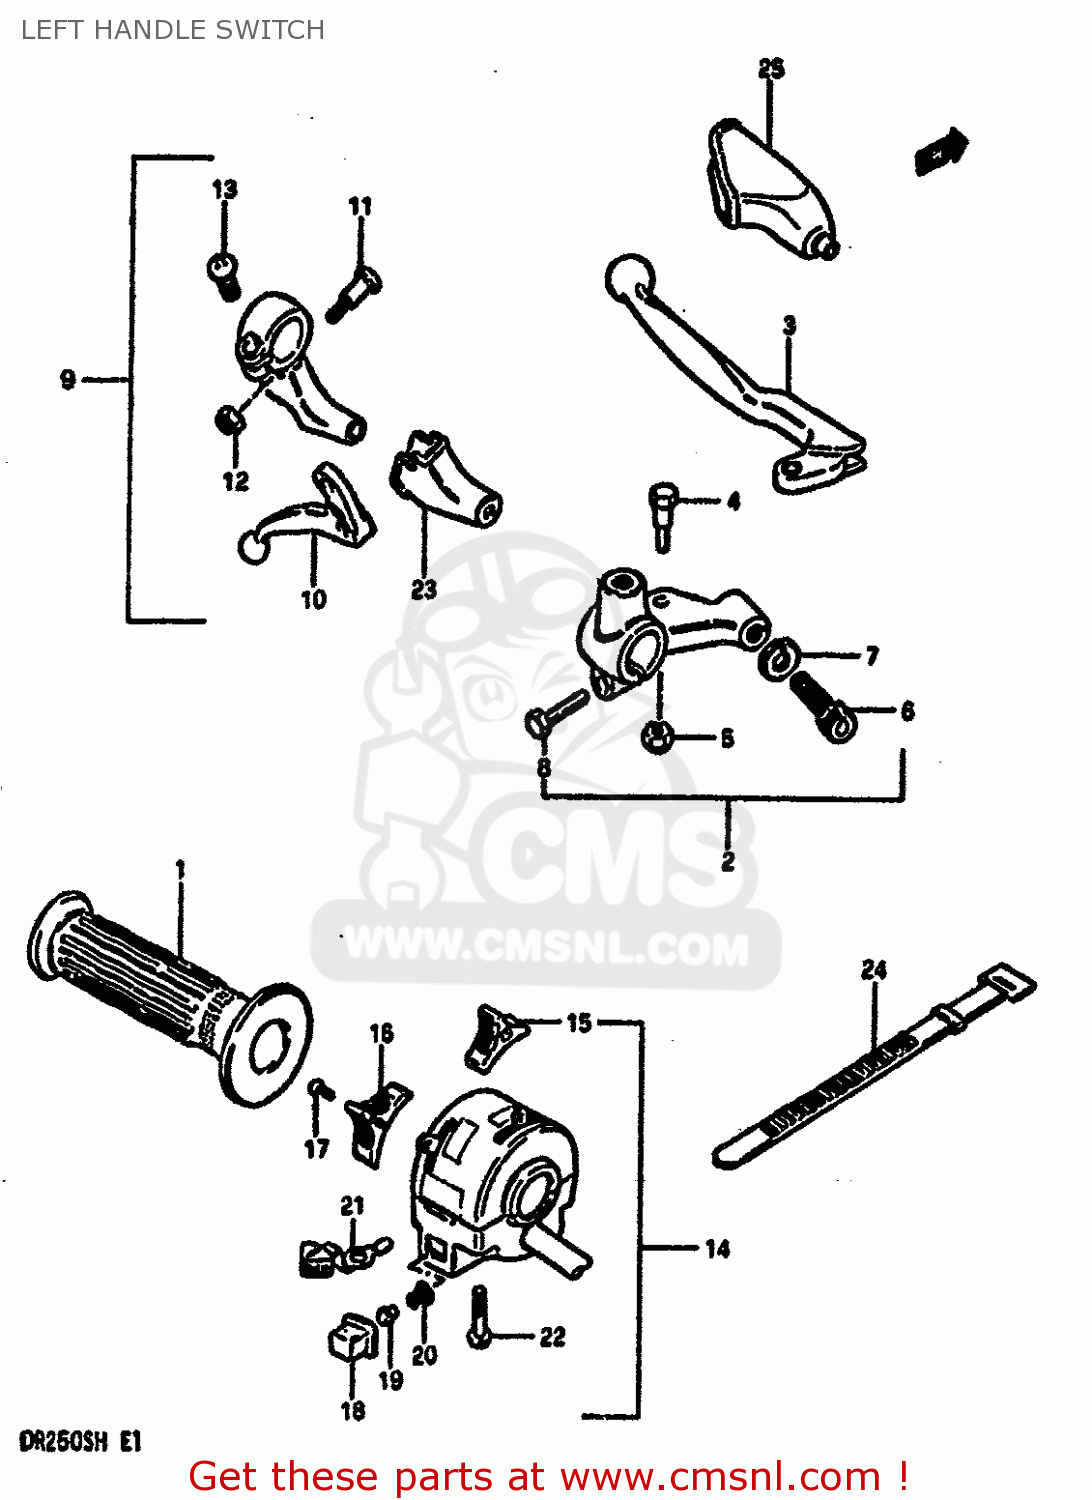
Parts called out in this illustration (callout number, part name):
1	GRIP,L
2	LEVER ASSEMBLY,CLUTCH
3	LEVER,CLUTCH
4	BOLT,LEVER
5	NUT 6MM
6	ADJUSTER,CABLE
7	NUT,CABLE ADJUSTER
8	BOLT,CLUTCH LEVER HOLDER
9	LEVER ASSEMBLY,DECOMPRESSION
10	LEVER,DECOMP
11	BOLT,LEVER
12	NUT
13	SCREW
14	SWITCH ASSY,HANDLE LH
15	KNOB,LIGHTING SWITCH
16	KNOB,DIMMER SWITCH
17	SCREW
18	BUTTON,HORN
19	CONTACT
20	SPRING
21	KNOB,TURNSIGNAL
22	SCREW
23	COVER,DECOMP LEVER DUST
24	CLAMP(L:120)
25	COVER,CLUTCH LEVER
